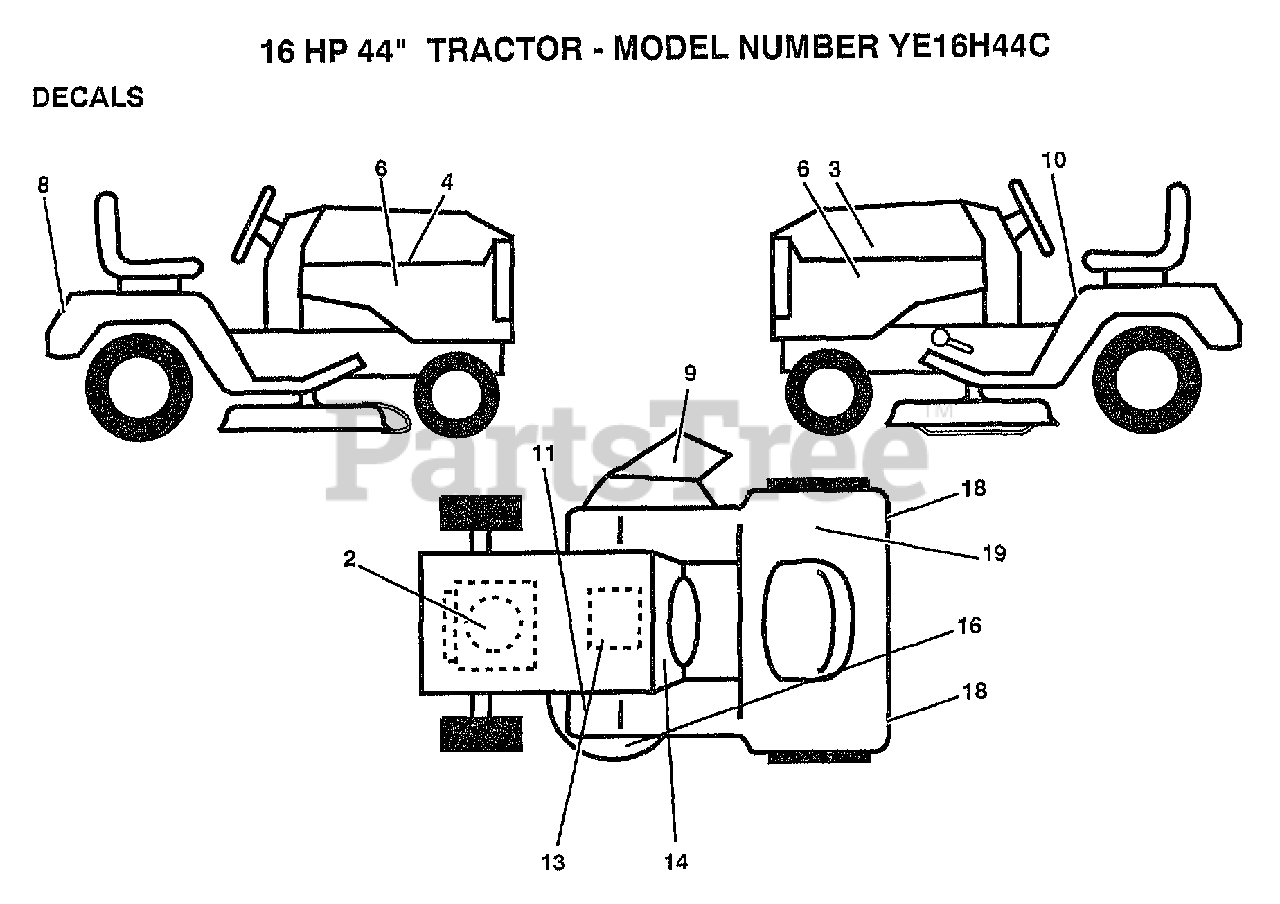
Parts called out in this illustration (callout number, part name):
2	DECAL.ENG.805720
3	DECAL HOOD LH
9	DECAL WARNING
10	DECAL CAUTION
11	DECAL T
13	DECAL
16	DECAL-INST YT
18	REFLECTOR-TAIL YT
